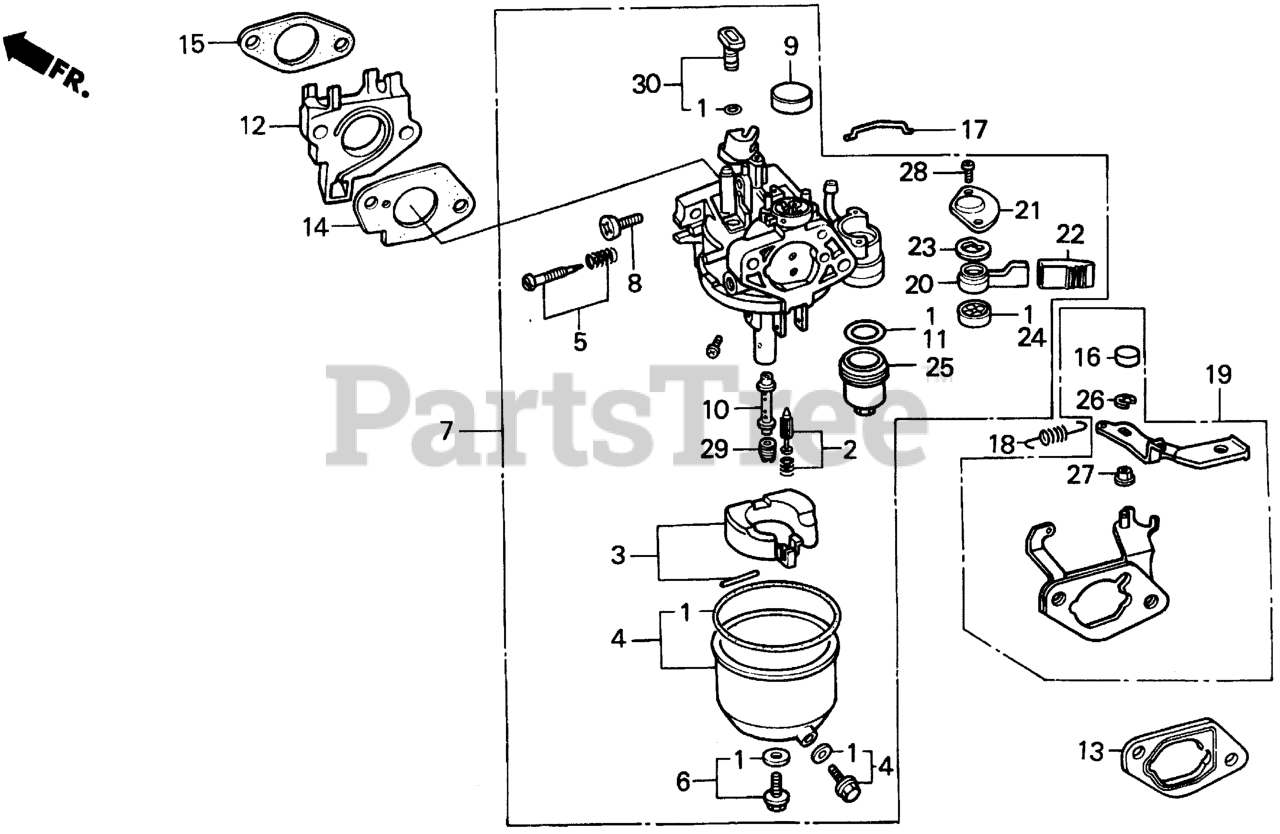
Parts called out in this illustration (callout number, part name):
1	GASKET SET
1	GASKET SET (INCLUDE 16173-001-004) (INCLUDES 16173-001-004)
2	VALVE SET, FLOAT
3	FLOAT SET
4	CHAMBER SET, FLOAT
5	SCREW SET, PILOT (Honda Code 1441500). (CARBURETOR NO.)
6	SCREW SET B
6	SCREW SET
7	CARBURETOR ASSY. (BE17A C)
7	CARBURETOR ASSY. (BE17A D)
7	CARBURETOR ASSY. (BE17A E)
8	SCREW, THROTTLE STOP
9	CAP, CHOKE LEVER DUST
10	NOZZLE, MAIN
11	GASKET, FUEL STRAINER CUP
12	INSULATOR, CARBURETOR
13	SPACER, CARBURETOR
14	GASKET, CARBURETOR
15	GASKET, INSULATOR
16	CAP, CHOKE LEVER
17	ROD, CHOKE
18	SPRING, CHOKE RETURN
19	STAY ASSY., CHOKE CONTROL
20	LEVER, VALVE
21	PLATE, LEVER SETTING (CARBURETOR NO.)
22	CAP, LEVER
23	SPRING, PETCOCK LEVER (CARBURETOR NO.)
24	GASKET, VALVE
25	CUP, FUEL STRAINER
26	E-RING (4MM)
27	BUSH, CHOKE LEVER
28	SCREW, PAN (3X8)
29	JET, MAIN (#88) Use from Engine SN BE27A B to BE27A E.
29	JET, MAIN (#90) Use up to Engine SN BE27A E.
29	JET, MAIN (#92) Use from Engine SN BB36B A.
30	JET SET, PILOT (#38)
